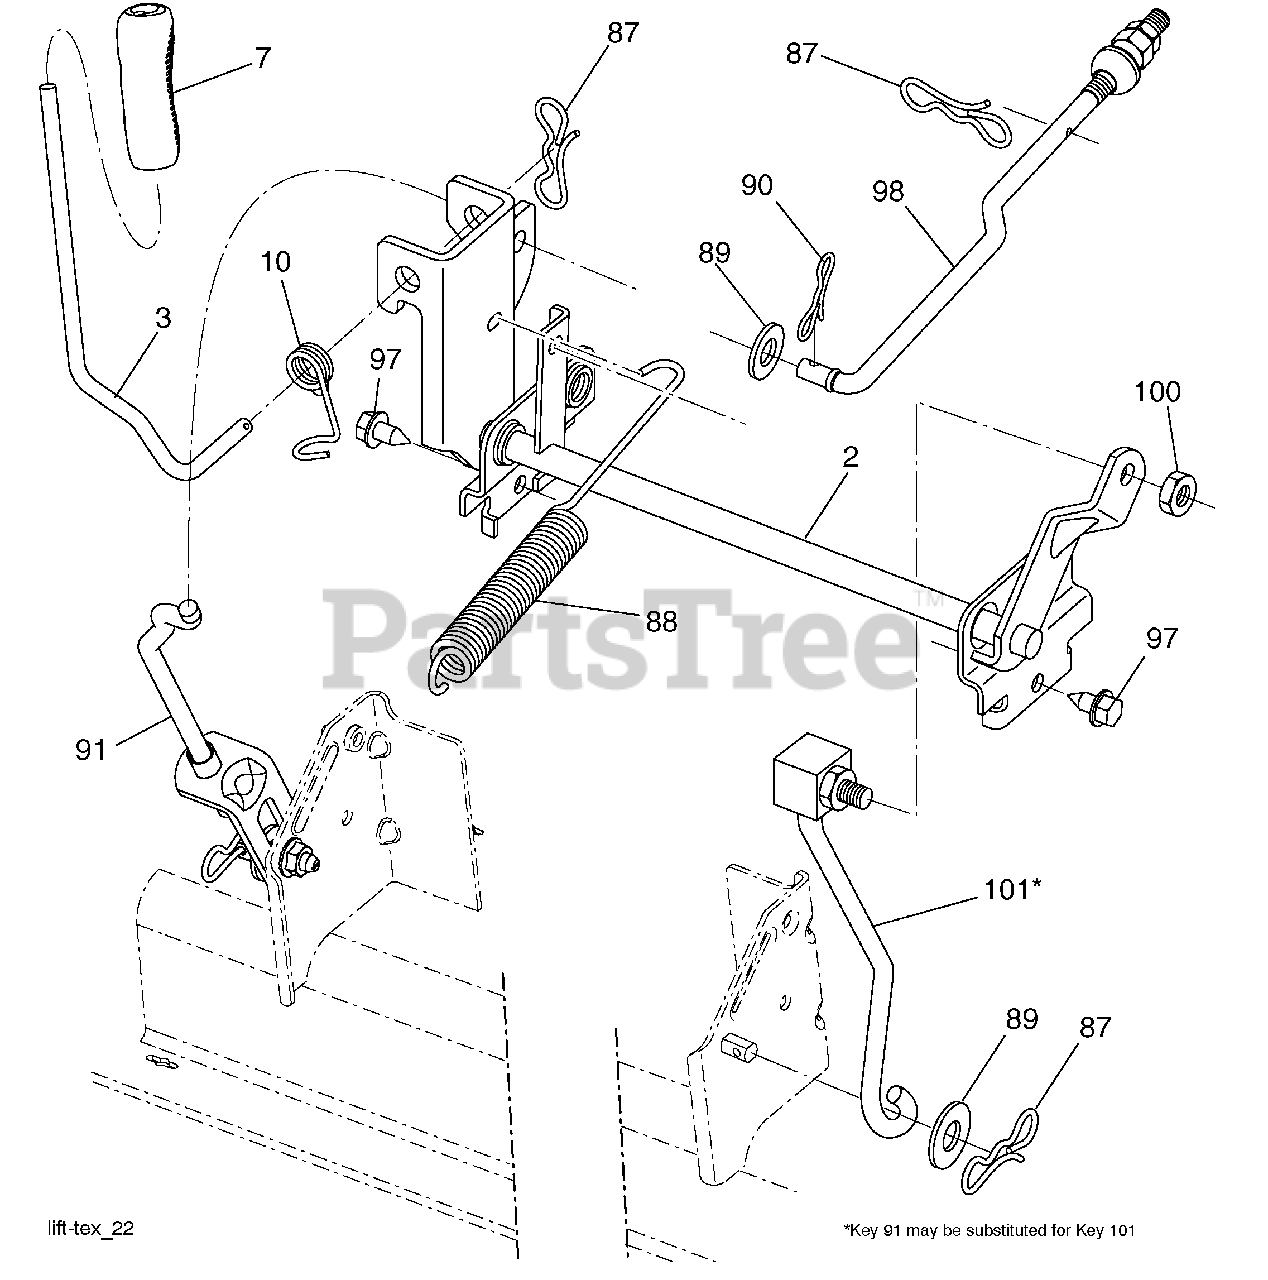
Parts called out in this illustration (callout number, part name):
2	Shaft Asm., Lift
3	Lever Asm., Lift RH
7	Grip, Lever
10	Spring Torsion
87	Pin Cotter 7/16 Bow Tie Lock
88	Spring Lift Assist
89	Washer Clear Zinc
90	Pin Cotter 5/16 Bow Tie Lock
91	Link Asm Lift LH Rear
97	Screw Hex Wsh. THDR 3/8-16 x 3/4
98	Link Lift Susp. Front Mower
100	Nut Centerlock 3/8-16 unc
101	Link Asm. Lift FXD
